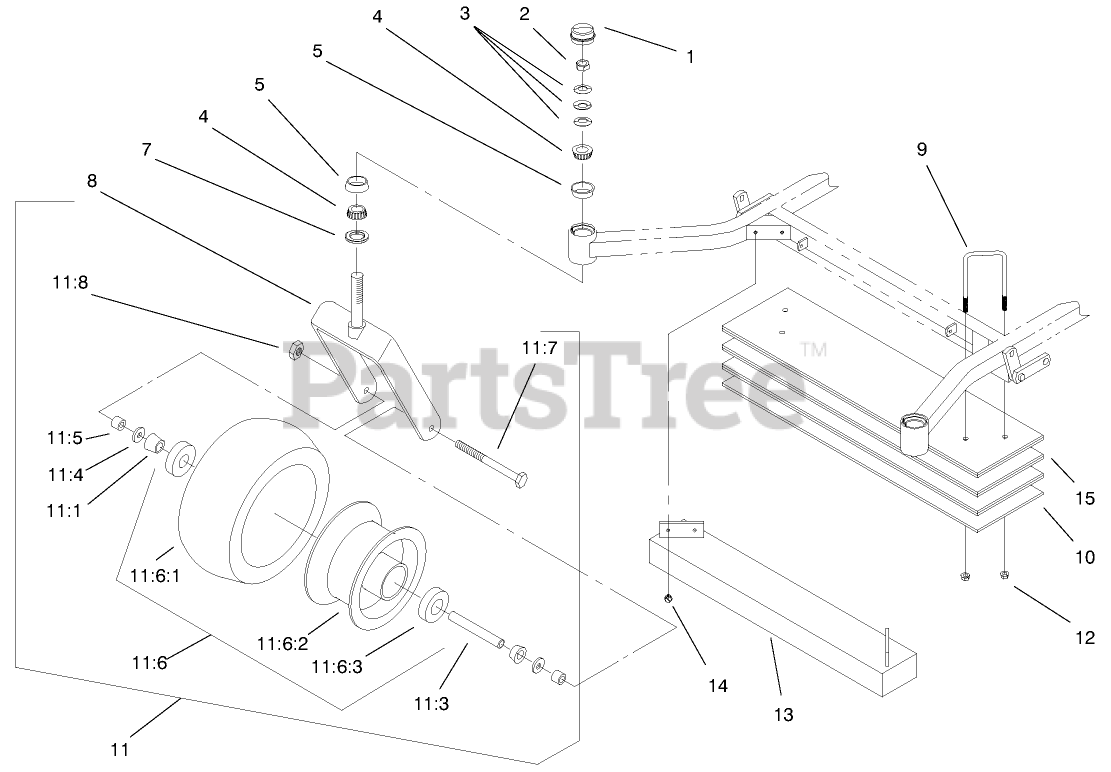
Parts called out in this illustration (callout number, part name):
1	Cap-Grease
2	LOCKNUT
3	Washer-Bellevue
4	BEARING-CONE, TAPERED
5	BEARING-CUP, TAPERED
7	Seal-Grease
8	Caster
9	U-BOLT
10	BAR-WEIGHT
11	Caster Wheel ASM
11:1	BEARING-CONE
11:3	Spacer
11:4	Seal-Bearing
11:5	Spacer-Bearing
11:6	Wheel & Tire ASM
11:6:1	Tire
11:6:2	Wheel
11:6:3	BEARING-ROLLER, CUP
11:7	SCREW-HH
11:8	NUT-LOCK, NI
12	NUT-HHF, WHIZ
15	WEIGHT BAR ASM
